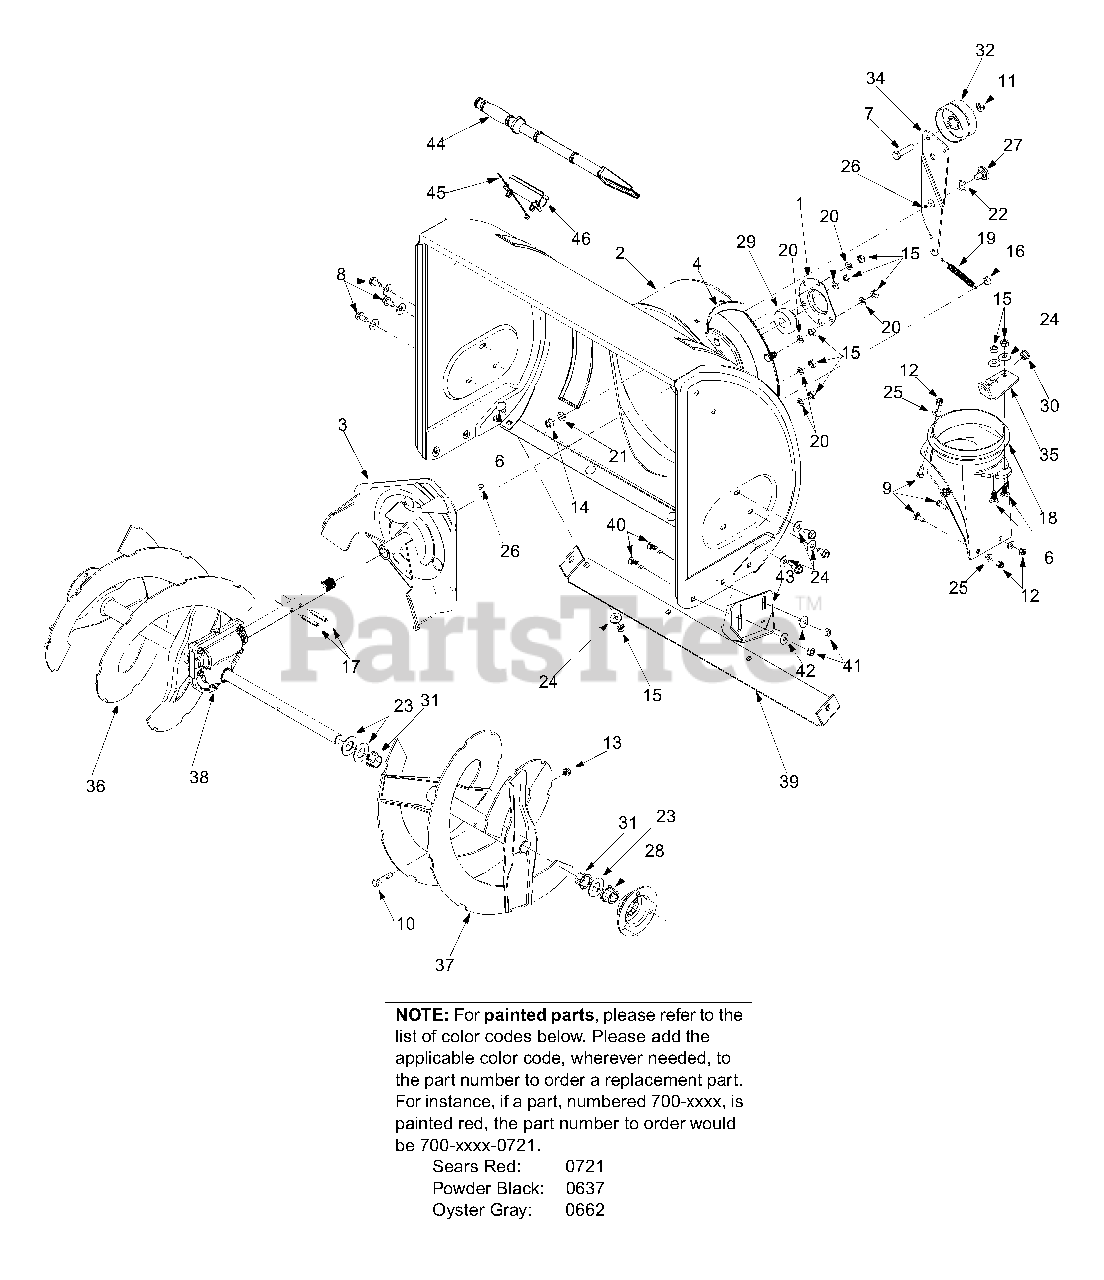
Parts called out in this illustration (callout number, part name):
1	Bearing Housing
6	Carriage Bolt 5/16-18 x .75" Gr.2
7	Hex Screw 3/8-24 x 1.5" Gr.5
8	AB Screw 5/16-12 x 1.0"
9	Carriage Screw 1/4-20 x .75"
10	Shear Bolt 5/16-18 x 1.5"
11	Jam Nut 3/8-24
12	Flange Nut 1/4-20
13	Hex Lock Nut 5/16-18
14	Hex Nut 3/8-16 Gr.2
15	Hex Nut 5/16-18 Gr.5
16	Hex Patch Nut 5/16-18
17	Spiral Pin
18	Chute Adapter
19	Extension Spring
20	Lock Washer
21	Lock Washer
22	Flat Washer
23	Flat Washer
24	Belleville Washer
25	Washer
26	Grease
27	Shoulder Screw
28	Hex Flange Bearing
29	Flange Ball Bearing
30	Bushing
31	Flange Bushing
32	Flat Idler
38	Gear Assembly: Auger 28"
40	Carr. Bolt: 5/16-18 x 0.75
41	Hex Nut: 5/16-18 Gr.5
42	Belleville Washer
44	Chute Clean-Out Tool
45	Cable Tie
46	Clean-Out Tool Mount
